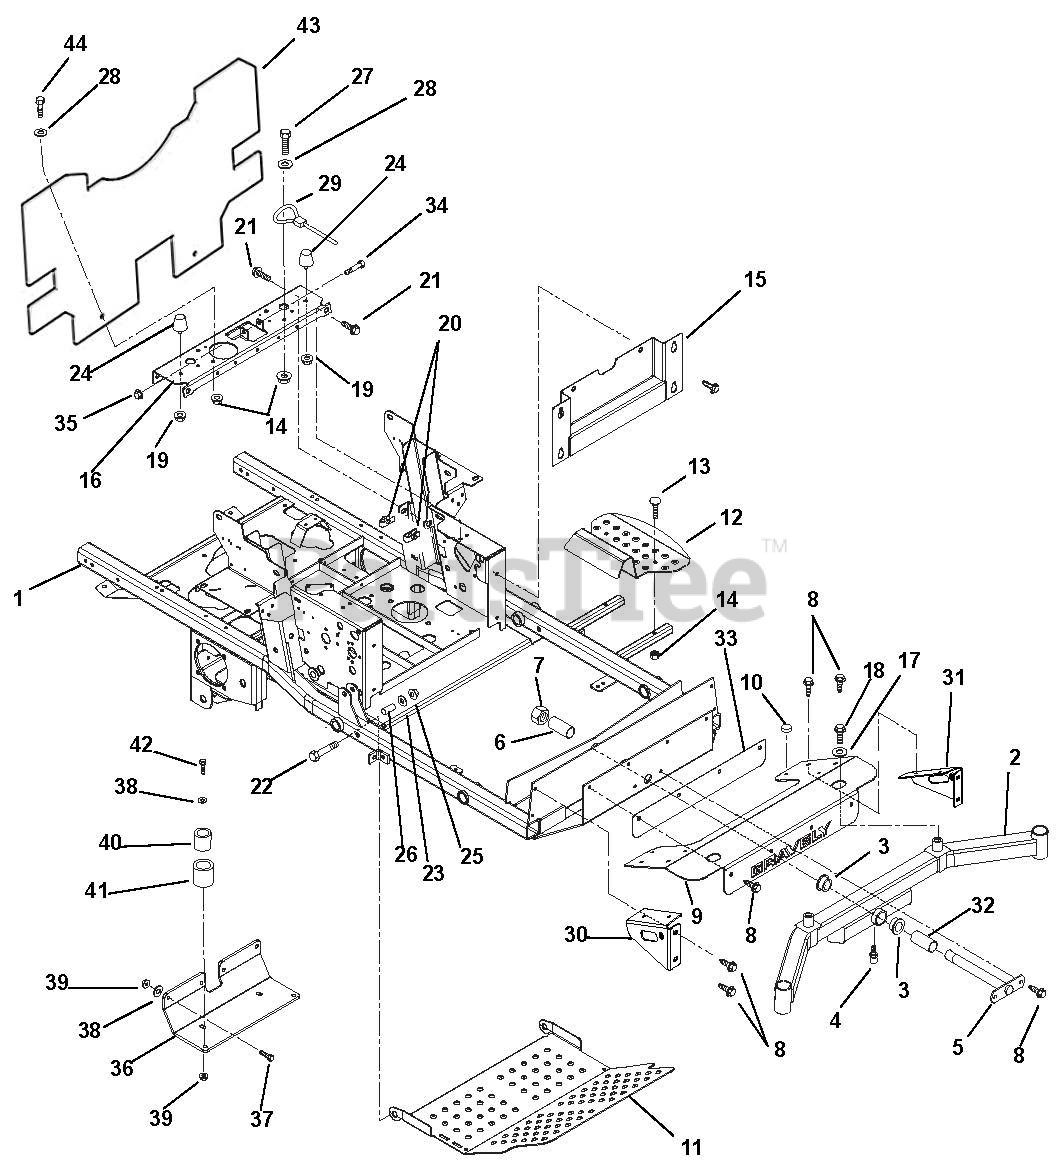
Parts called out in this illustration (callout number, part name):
1	Weldment, Frame
2	Weldment, Axle
3	Bushing, Flange 1.25 x 1.50 x 1.00 x .200
4	Fitting, Lube 45 Degree GM411031
5	Pin, Axle
7	Nut, Locking Nylon 1.00-14
8	Screw, Tapping .38-16 x .75
9	Axle Cover
10	Button, Rubber
11	Panel, Inspection
12	Step, Ingress
13	Bolt, Round Head Square Neck .31-18 x 1.75 Grade 5
14	Nut, Locking Top Flange .31-18
15	Plate, Kick
16	Channel, Cross
17	Washer, Flat .640 x 1.75 x .250
18	Bolt, Hex .50-20 x 1.00 Grade 5
19	Nut, Locking Flange .312-18
20	Nut, Retainer .375-16 x .37
21	Bolt, Serrated Hex Flange Washer Head .38-16 x 1.00
22	Bolt, Hex .50-13 x 3.25 Grade 5
23	Washer, Flat Steel .563 x 1.38 x .109
25	Nut, Locking Top Flange .50-13
26	Bushing, Flange .515 x .75 x .275 x 1.12
27	Bolt, Hex .31-18 x .75 Grade 5
28	Washer, Flat Steel .344 x 1.25 x .135
29	Cable, Seat Prop
30	Weldment, Right Axle Cover Support
31	Weldment, Left Hand Axle Cover Support
32	Spacer, 1.25OD x 1.0ID x 3.63
33	Plate, Backer
34	Bolt, Hex .38-16 x 3.00 Grade 5
35	Nut, Locking Top Flange .38-16
36	Bracket, Support Arm Frame
37	Bolt, Hex .50-13 x 1.25 Grade 5
38	Washer, Flat Steel .531 x 1.06 x .095
39	Nut, Locking Top Flange .50-13
40	Spacer, .563 x 1.25 x .969
41	Spacer, .563 x 2.00 x 2.00
42	Bolt, Hex .50-13 x 4.50 Grade 5
43	Guard, Grass
44	Bolt, Hex .31-18 x 1.00 Grade 5
